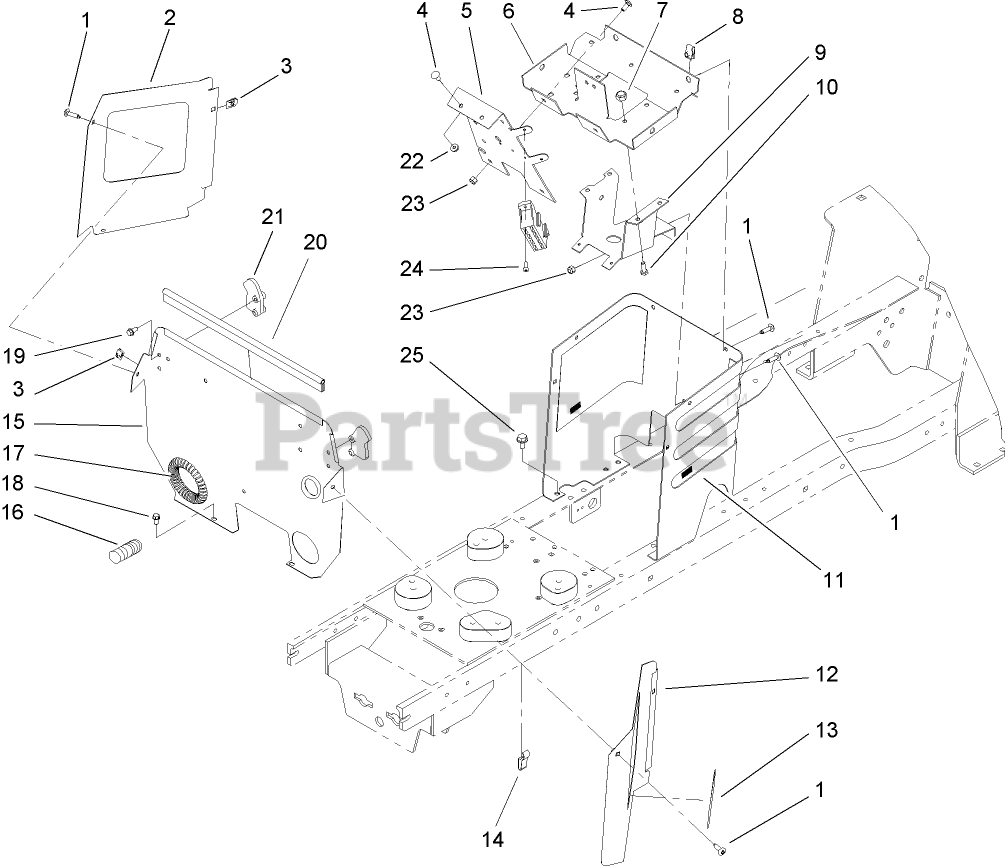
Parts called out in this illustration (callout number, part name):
1	SCREW-HH
2	RH SIDE COVER ASM
4	SCREW-CARR
5	PANEL-SUPPORT, DASH
6	SUPPORT-DASH
7	NUT-HEX
9	BRACKET-COLUMN, LOWER
10	SCREW-HH
11	HOODSTAND ASM
12	LH COVER ASM
14	CLAMP-CASING
17	COVER-SHAFT, DRIVE
18	SCREW-HWH
19	SCREW-PLASTITE
20	TRIM-SEAL, FIREWALL
21	LATCH-HOOD
22	NUT-KEPS
23	NUT-LOCK, NI
24	SCREW-PPHTF
25	SCREW-HWHTF
